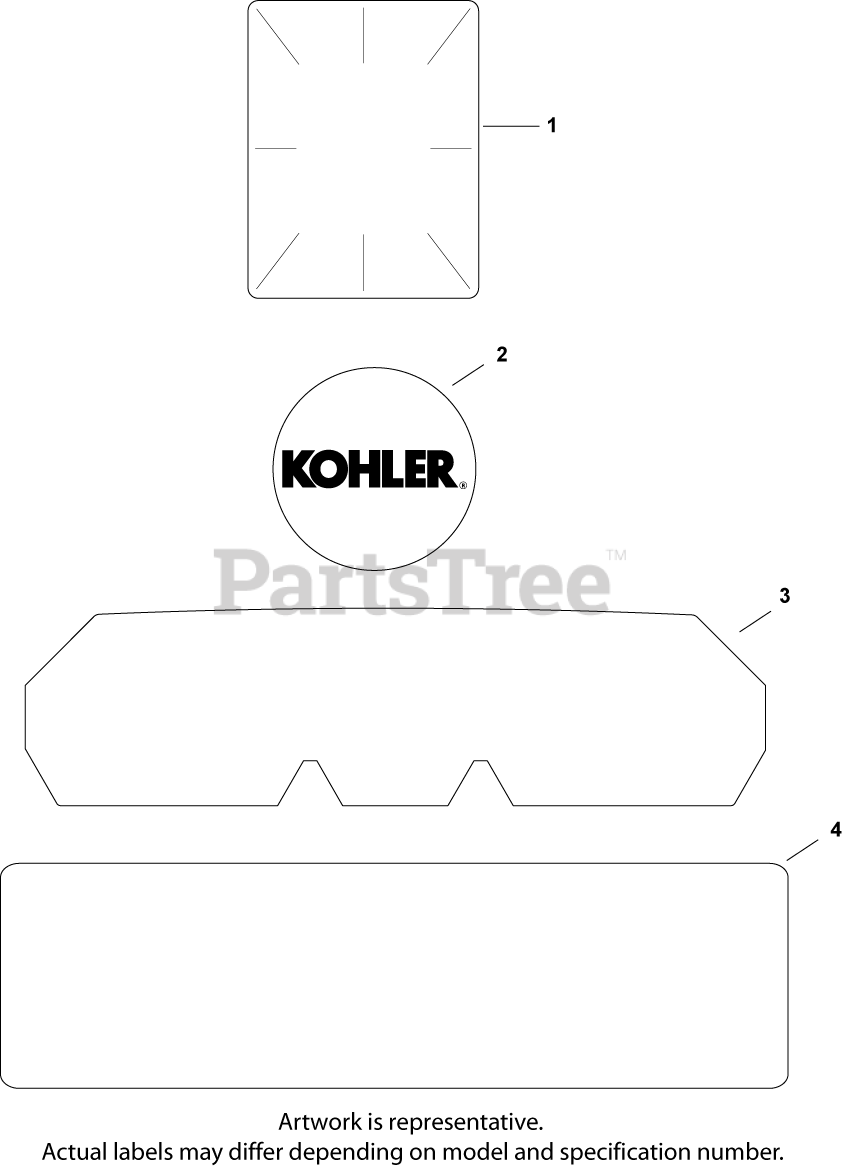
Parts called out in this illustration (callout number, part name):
1	DECAL, CLEAR LAMINATE USE 25 113 70-S
2	DECAL, GRASS SCREEN USE 24 113 499-S
3	DECAL, HEAT REFLECTIVE
4	DECAL, 20 HP - DISCONTINUED
